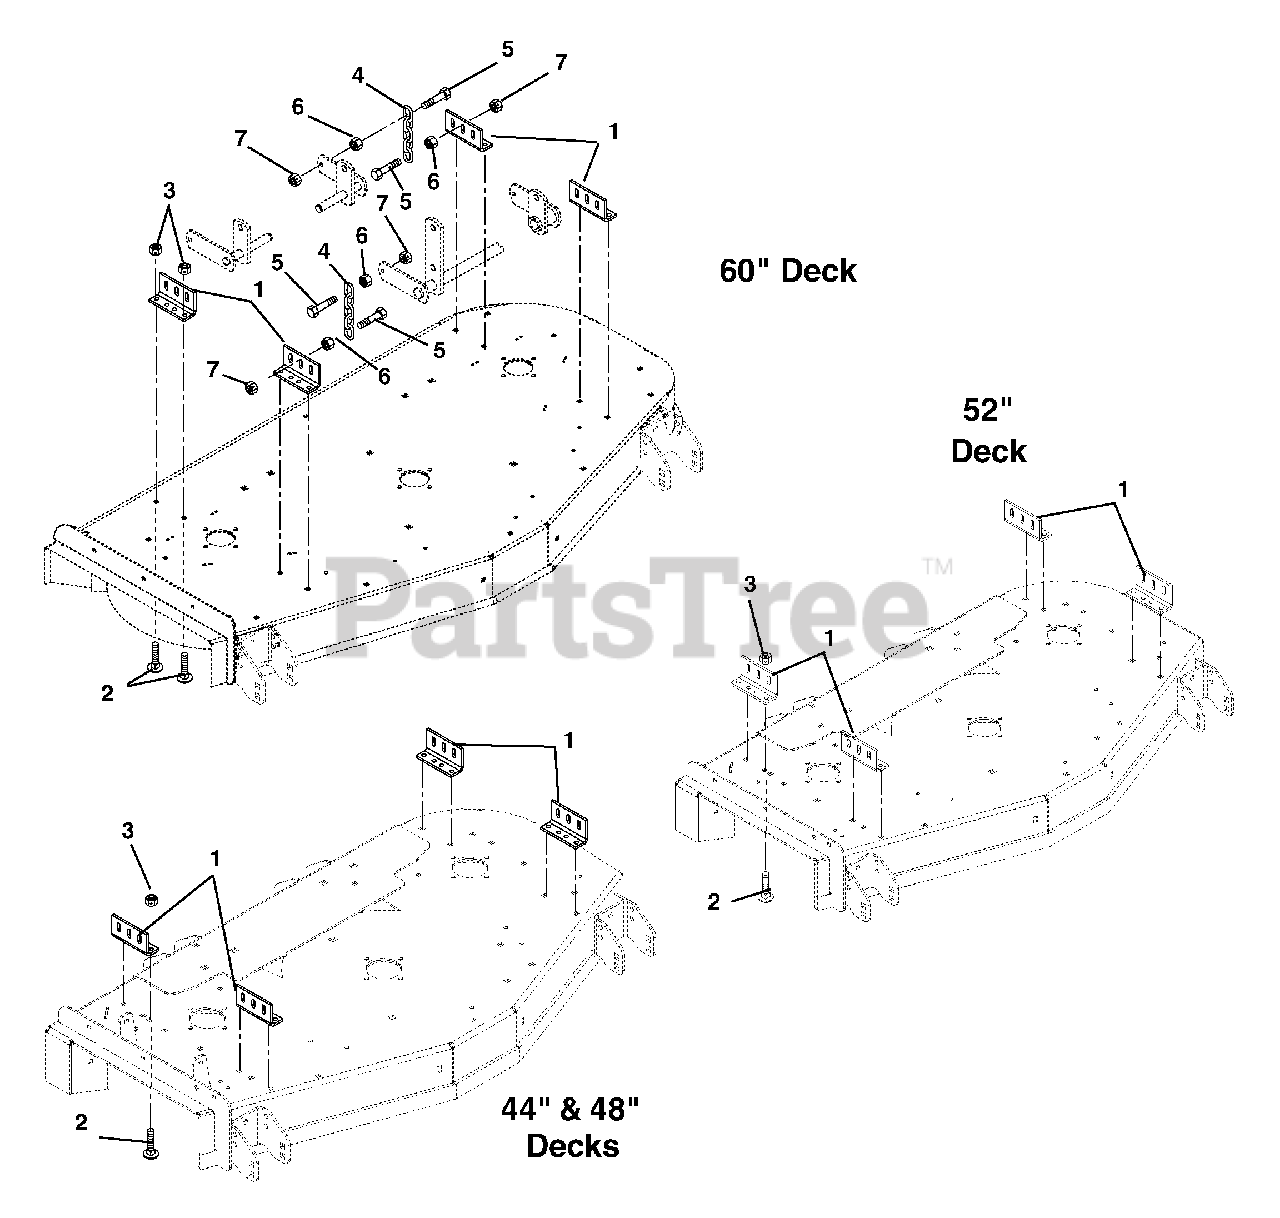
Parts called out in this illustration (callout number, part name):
1	Bracket, Mower Mounting
2	Bolt, Round Head Square Neck .38-16 x 1.00 Grade 2
3	Nut, Locking Top Flange .38-16
4	Chain, Link
5	Bolt, Hex .50-13 x 2.00 Grade 5
6	Nut, Spin Lock Flange .50-13
7	Nut, Locking Top Flange .50-13
